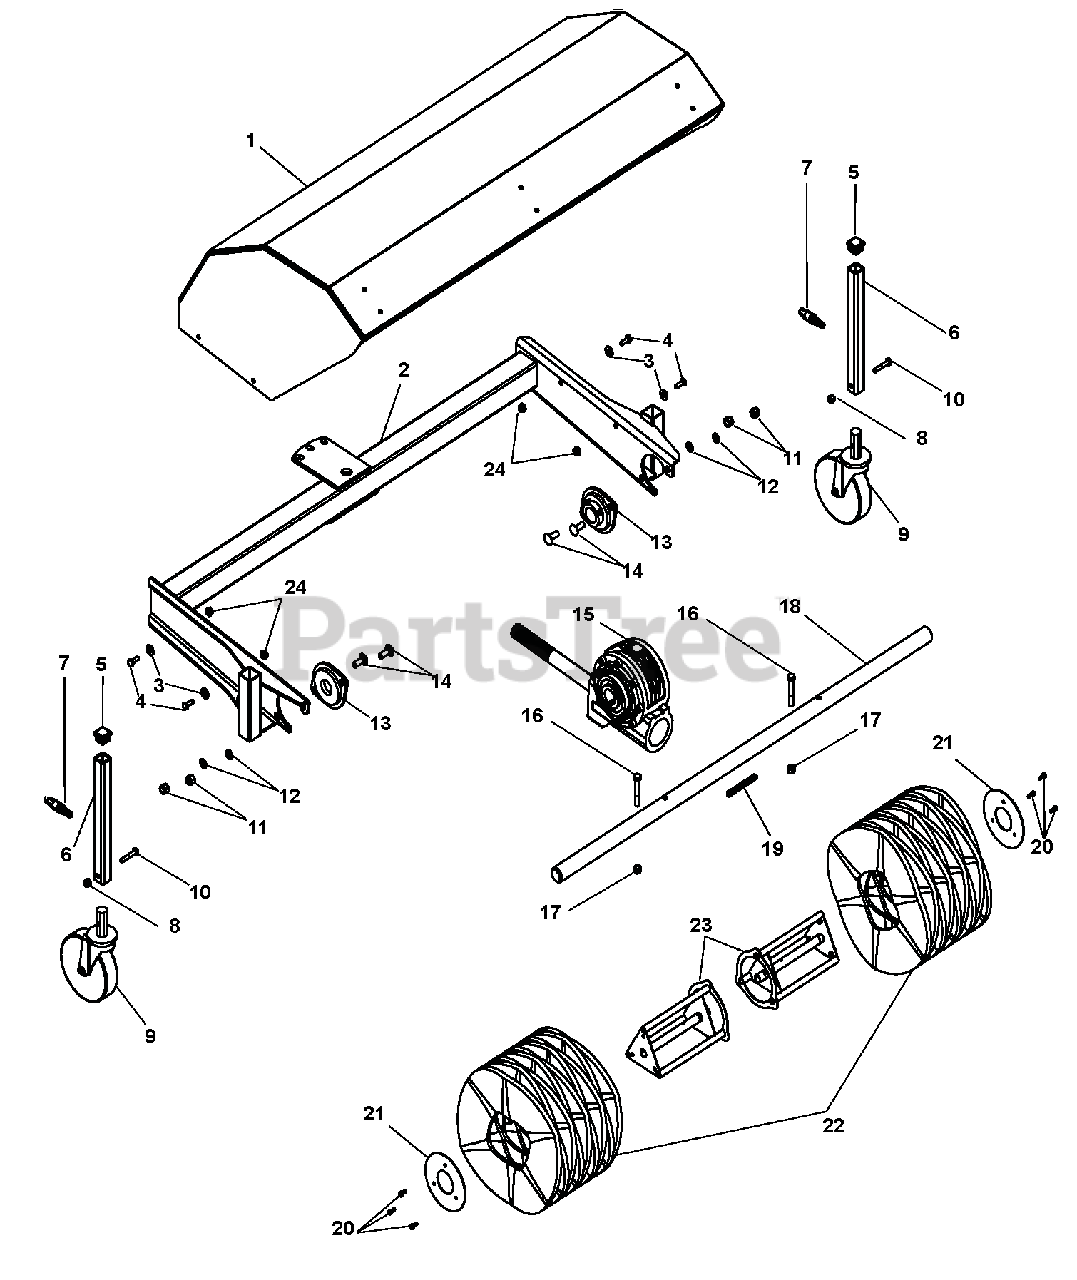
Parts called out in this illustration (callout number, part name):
1	HOOD, 36" BRUSH - W/DECALS
2	FRAME, BRUSH-W.U. 3' BRUSH
3	@WSHR-FL-STL.312X.734X.065 YWZ
4	@BLT-HEX .25-20X.75 GR5 YWZC
5	PLUG, SQUARE-1" PLASTIC
6	LEG, CASTER WHEEL
7	KNOB, BLACK
8	@NUT-LK-NYL .250-20 YWZC
9	CASTER WHEEL,5"X1.250" 7/8 STE
10	@BLT-HEX .25-20X1.50 GR5 YWZC
11	@NUT-LK-NYL .38-16 YWZC
12	WASHER, SAE 3/8
13	BEARING, 1 1/8" FLANGETTE
14	@BLT-RDHDSQNK .38-16X1.00 G5YZ
15	GEARBOX, WORM ALUMINUM-8.25:1
16	@BLT-HEX .31-18X2.25 GR5 YWZC
17	@NUT-LK-NYL .312-18 YWZC
18	SHAFT, THRU 1-1/8 X 3' MCD
19	KEY, SQUARE .25X.25X3 LG
20	HHCS, SERRATED FLANGE 3/8-16X1
21	PLATE, END RETAINER
22	KIT, BRISTLE - SET OF 18
23	KIT-36" BRUSH DRV CORE REPL
24	@NUT-LK-TOP-FLG .25-20 YWZC
